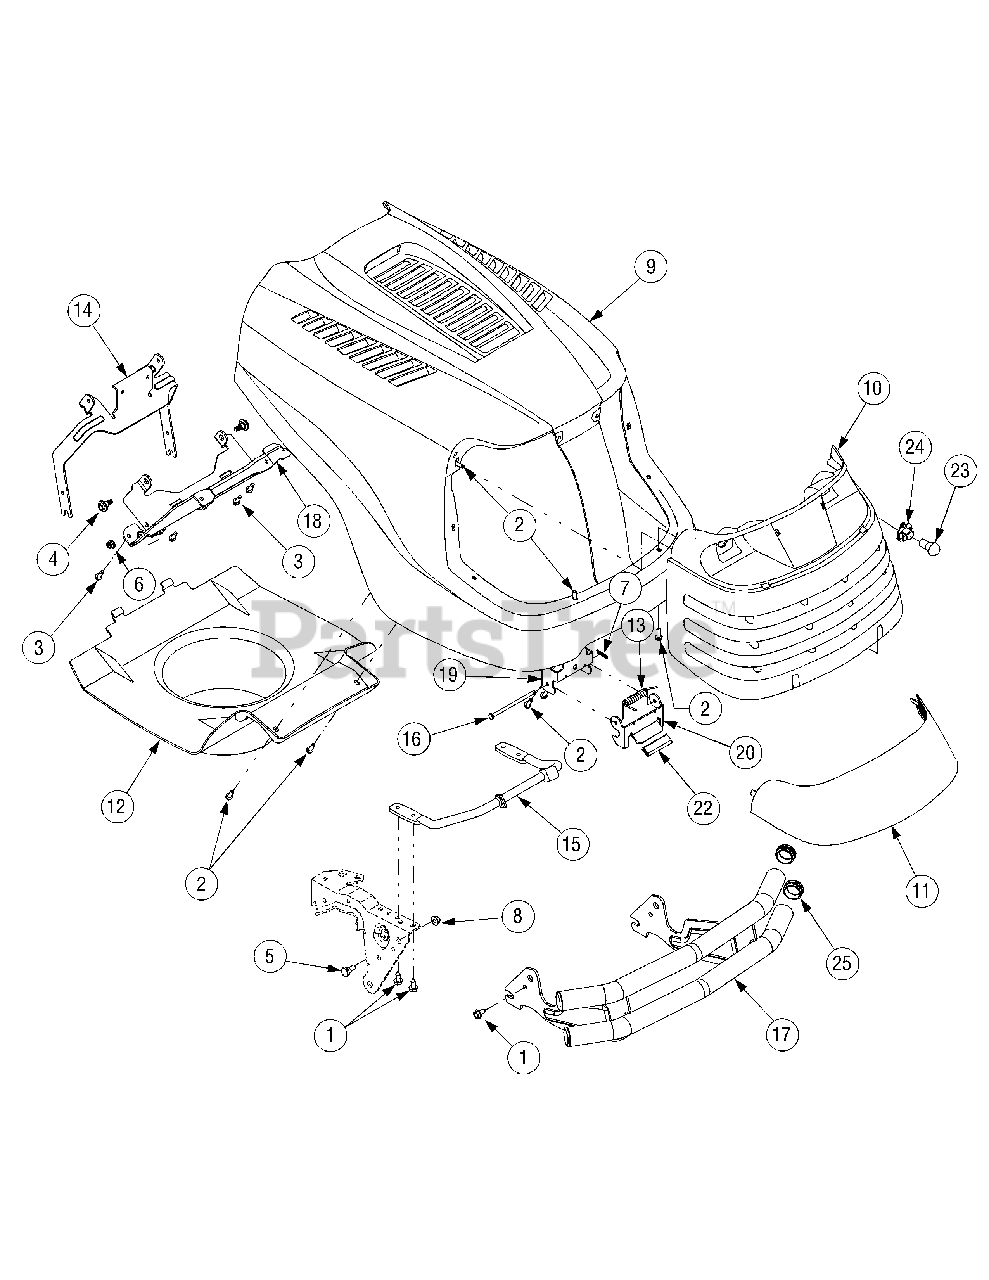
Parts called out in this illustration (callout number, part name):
1	Screw, 5/16-12 x.750
2	Screw, 1/4-15 x.750
3	Screw, Self Tapp, 1/4-20 x.750
4	Screw, Shoulder, 5/16-18
5	Bolt, Shoulder, 3/8-16
6	Nut, Flange Lock, 5/16-18
7	Pin, Cotter,.072 Dia. x 1.13
8	Nut, Nylon Lock, 3/8-16
9	Hood, Service Kit
9	Hood
9	Push Nut .25ID x .50 OD
9	Screw, Hi Low 5/16-14 x .75
10	Grill
11	Lens
12	Hood Plenum
13	Latch Spring
15	Hood Latch Rod
16	Rod,.250 Dia. x 4.55
19	Latch Plate
20	Latch Pivot Bracket
21	Screw, 5/16-18 x.50
22	Vinyl Strip, 2.5"
23	Miniature Lamp, 12V
24	Lamp Socket
25	Cap, Bumper
